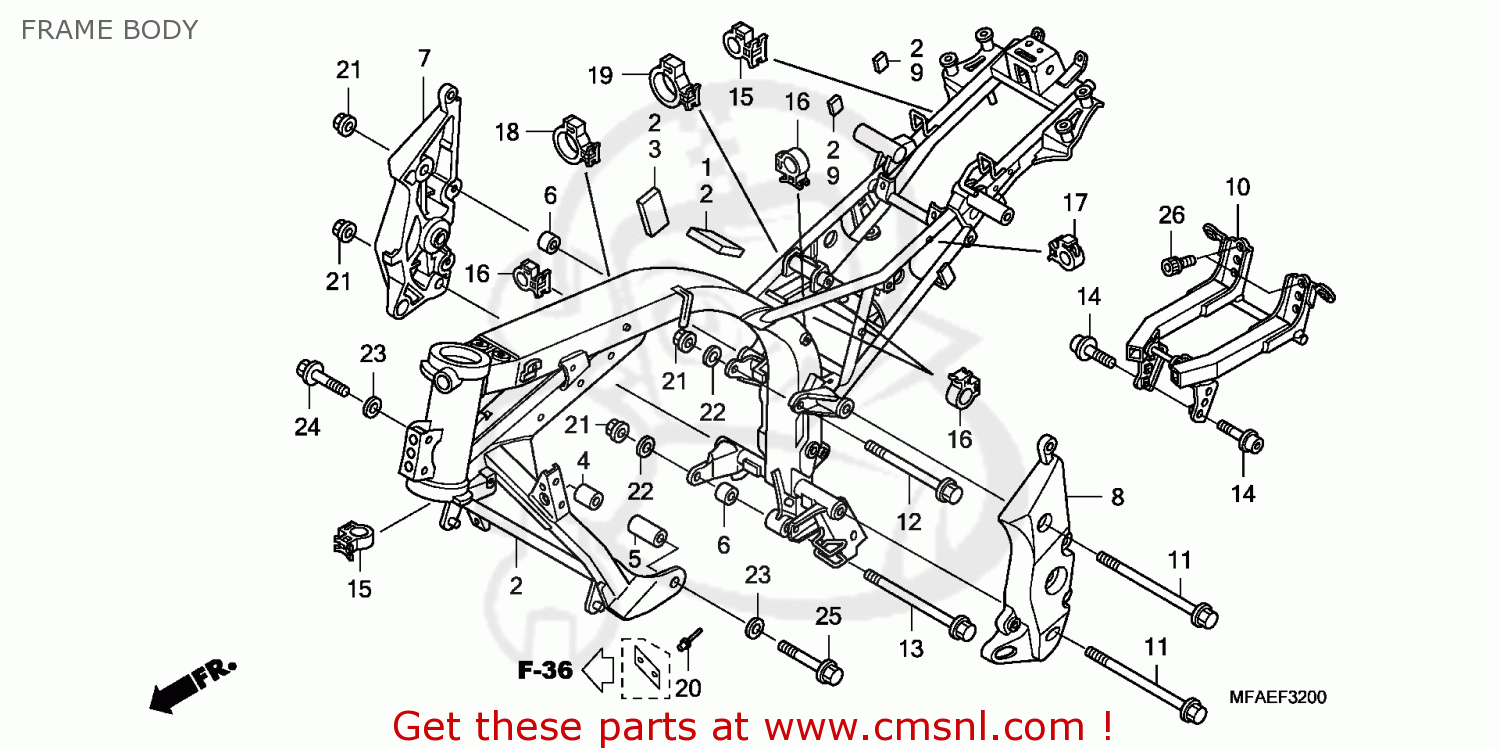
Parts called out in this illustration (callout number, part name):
1	CUSH FUEL TANK RR
2	BODY SET,FRAME
3	RUBBER,BATTERYCUS
4	COLLAR R,FR ENG.H
5	COLLAR L,FR ENG.H
6	COLLAR R,FR ENG.H
7	BRKT,R PI*NH437M*
8	BRKT,L PI*NH437M*
9	RUBBER B,PROTECTO
10	BRKT.COMP.,SEAT A
11	BOLT,ENG HANG 12X
12	BOLT,FLANGE 12X19
13	BOLT,FLANGE 12X21
14	BOLT,FLANGE SOCKE
15	CLIP,CABLE,10MM
17	CLIP,CABLE,15MM
18	CLIP,CABLE,25MM
19	CLIP,CABLE 30MM
20	RIVET,SCW,2.5X9
21	NUT, FLANGE, 12MM
22	WASHER,PLAIN,12MM
23	WASHER,PLAIN 12MM
24	BOLT,FLANGE,DR,12
25	BOLT,FLANGE,DR,12
26	BOLT,SOCKET,8X16
